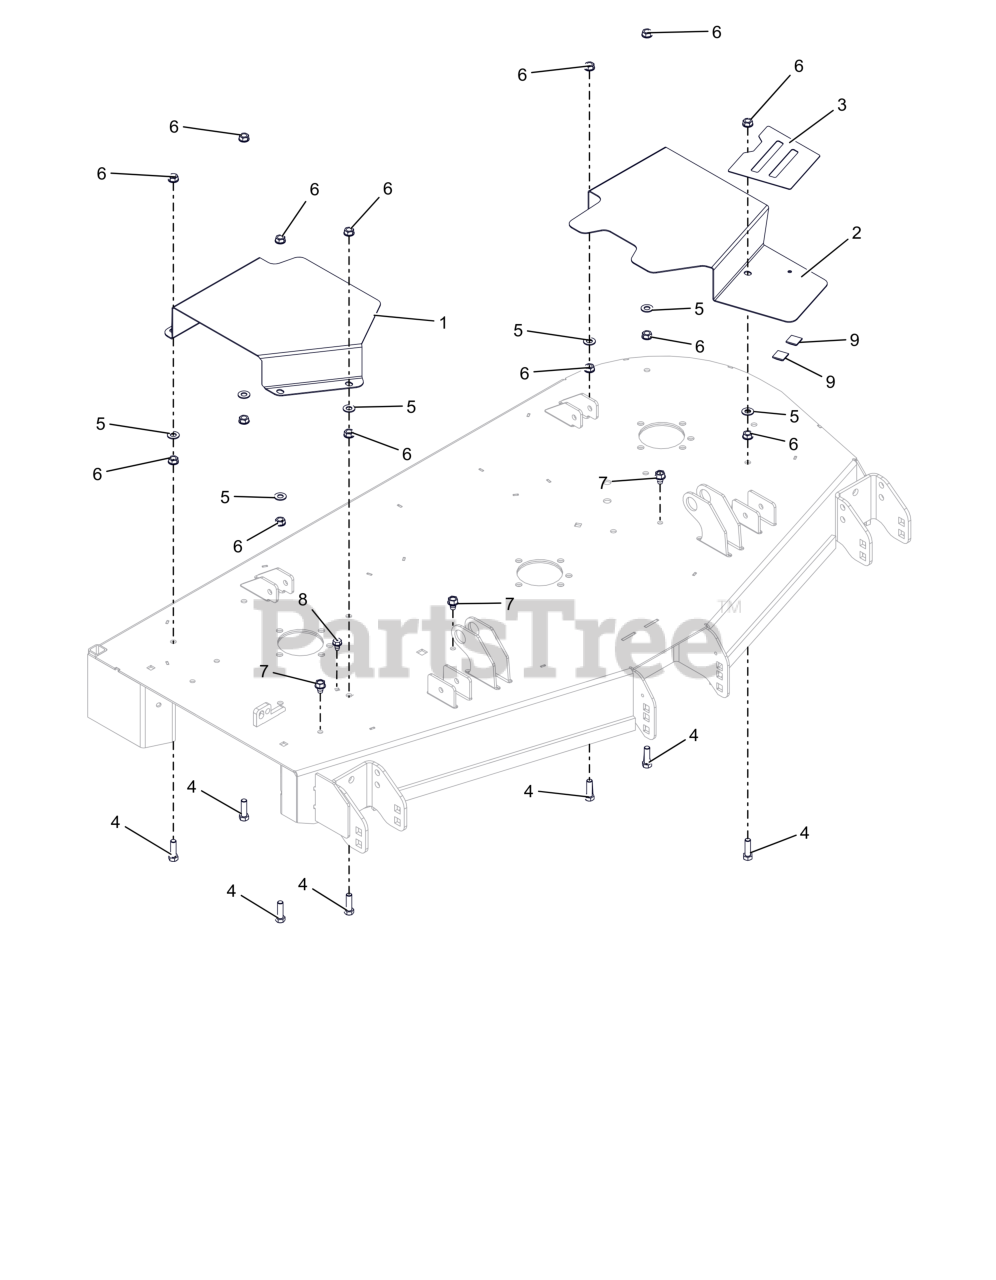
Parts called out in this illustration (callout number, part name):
1	COVER, BELT 52" & 60" RIGHT
2	COVER, BELT 52" LEFT
3	GRIP TAPE 52-60 BELT COVER
4	BLT, HEX .38-16X1.25 G5 ZCC
5	WSHR,FLT .406X.812X.065 ZCC
6	NUT, SPNLK-FLG .38-16 G5 ZCC
7	SCR,TAP .375-16X.50 HWH TR ZCC
8	SCR,TAP .312-18X.50 HWH TR ZCC
